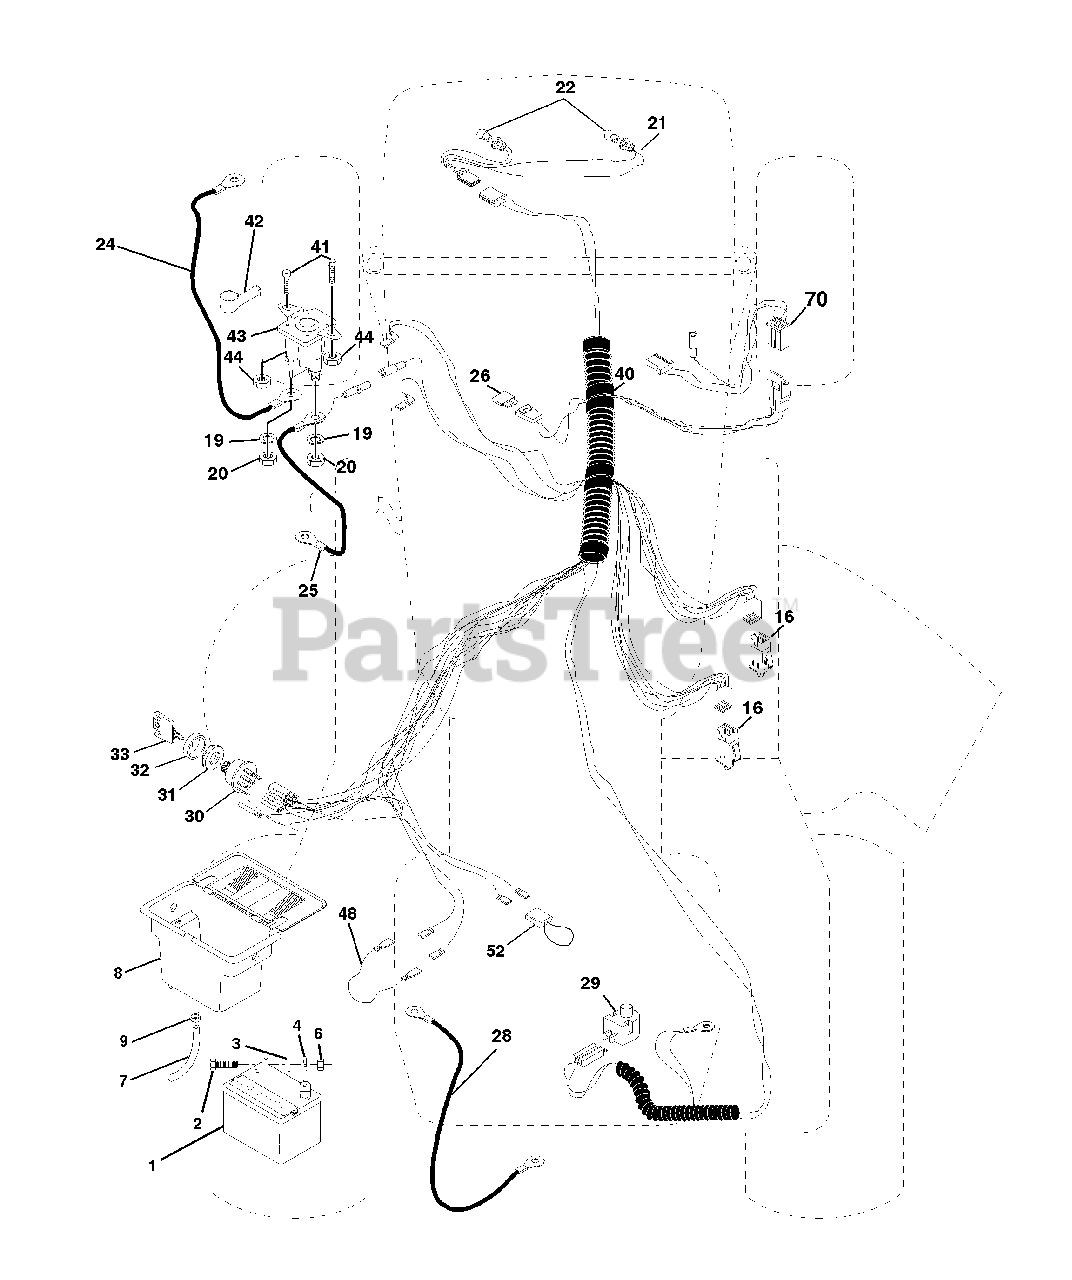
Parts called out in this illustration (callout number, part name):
1	Battery 12 Volt 25 AMP
2	Bolt Hex Hd 1/4-20unc X 3/4
3	Washer 9/32 X 5/8 X 16 Ga.
4	Washer Lock Hvy Helical 1/4
6	Nut Fin Hex 1/4-20 Unc
7	Tube Plastic 12"
8	Case Battery Mech Hinge
9	Clamp Hose Olive
16	Switch Interlock Push-In
19	Washer Lock 1/4
20	Nut Jam Hex 1/4-20 Unc
21	Harness Asm Light W/4152j
22	Bulb Light #1156
24	Cable Battery 6 Ga 11" red
25	Cable Battery 6 Ga 44" red w/16 wire
26	Fuse 30 AMP Auto Green
28	Cable Ground 6 Ga 12" black
29	Switch Plunger Nc Gray
30	Switch Ign 4 pos w/lights
31	Nut Ignition
32	Cover Sw Ignition
33	Key Ign Modelled Generic
40	Harness Ign.
41	Bolt Blk Fin Hex 1/4 - 20 x 1/2
42	Cover Terminal Red
43	Solenoid
44	Nut Keps Hex 1/4-20 Unc
48	Adapter Ammeter Rectangular
52	Protection Wire Loop
70	Harness, Eng. B&S/Tec Dual
